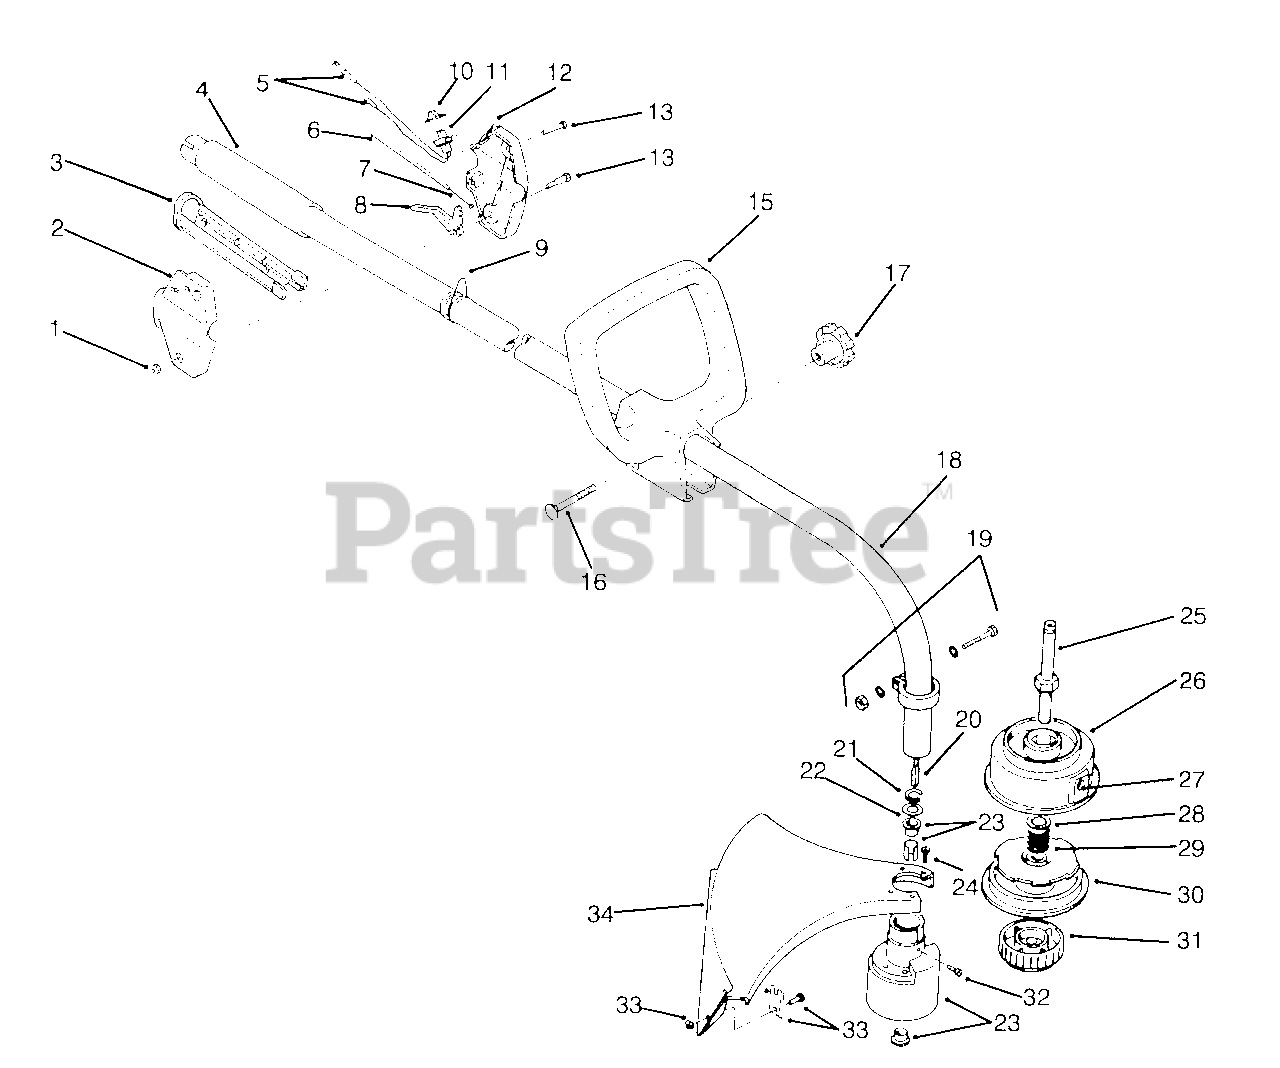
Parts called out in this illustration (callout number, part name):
1	Nut-Lock
2	Housing-R.H.
5	Assembly-Lead Wire
6	Housing-Throttle Cable
7	Cable-Throttle
8	Lever-Throttle
9	Clamp-Shoulder Strap
10	Cap-Switch
12	Housing-L.H.
13	Screw-Hex. Hd.
16	Bolt-Carriage
17	Knob-Loop Handle
18	Assembly-Drive Shaft
19	Assembly-Lower Clamp
20	Flexible Drive Shaft
21	Ring-Retaining
23	Assy.-Bushing Housing
24	Assy.-Guard Mount Screw
25	Shaft-Spool
26	Assy-Outer Spool & Eyelet
28	Retainer (10 Pack)
30	Inner Reel
31	Assy-Bump Head Knob
32	Anti-Rotation Screw
33	Assembly-Blade (Incl. 2 Screws/2 Nuts)
34	Assembly-Guard & Blade (Incl. Ref. #33)
